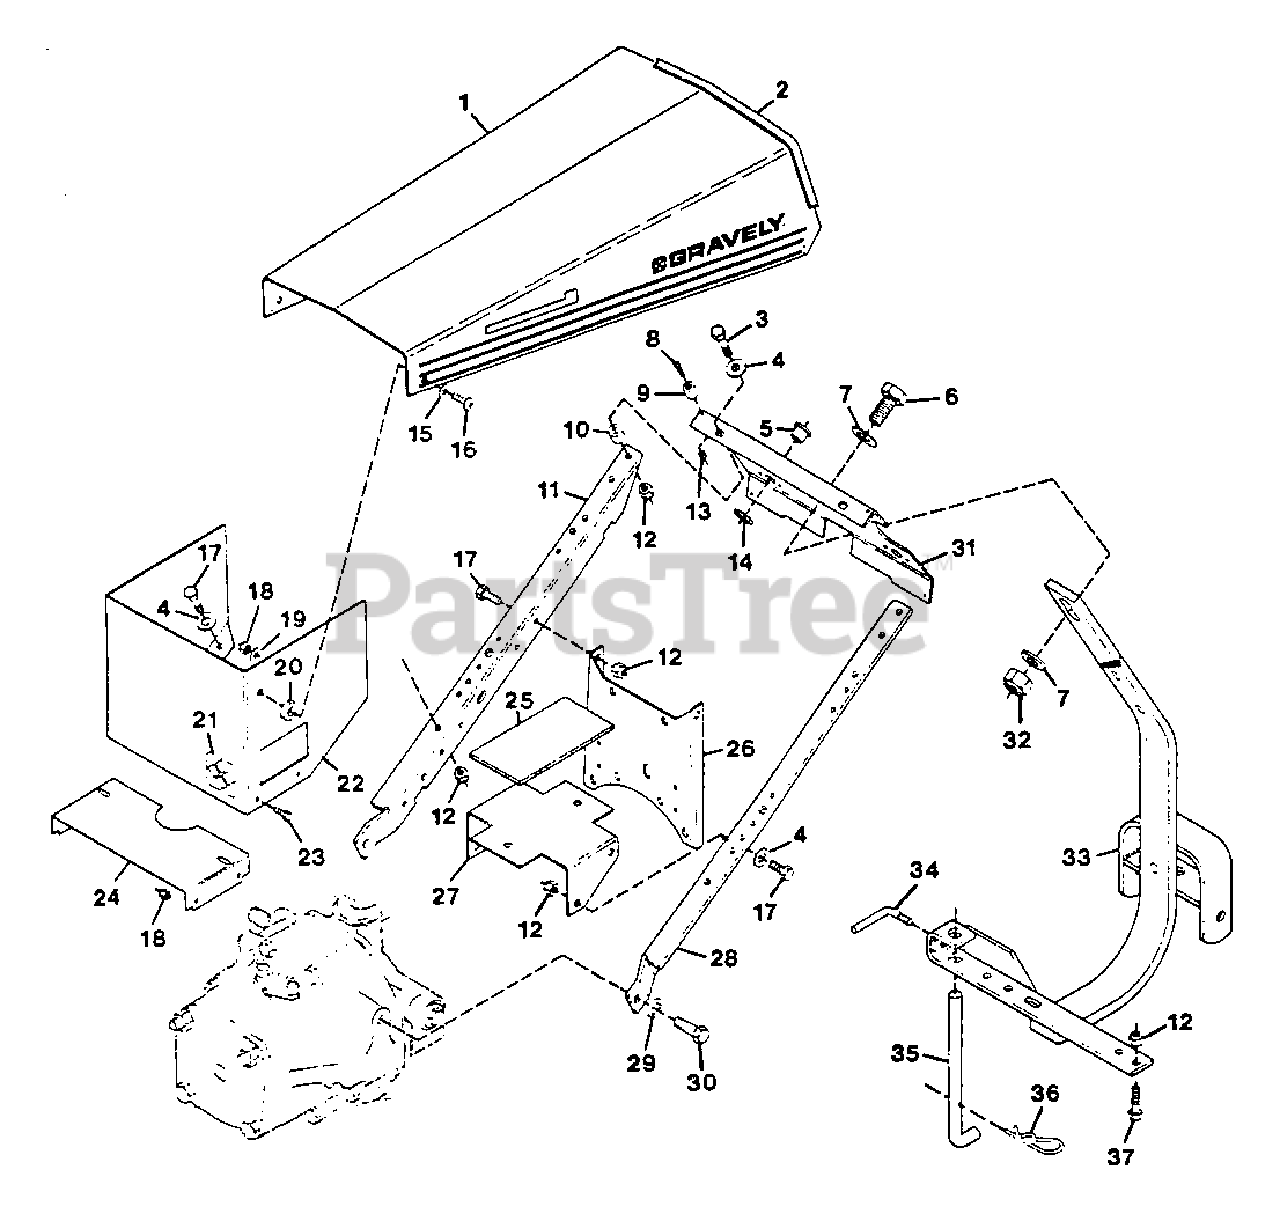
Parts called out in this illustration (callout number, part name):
1	Assembly, Hood
2	Ft. Strip, Cowl
3	Bolt, Hex 3/8-16x1.50
4	Washer, Flat .406x.812x.065
5	Bushing, .513x.750x.625
6	Bolt, Hex 5/8-11x2.00
7	Washer, Flat .656x1.250x.100
8	Screw, Mach. 6-32x.625 PHD
9	Bumper
10	Bushing, Reverse Idler
11	Support, Handlebar R.H.
12	Nut, Lock 3/8-16
13	Nut, Mach. Lock 6-32
14	Ring, Retaining
15	Washer, Flat .281x.625x.065
16	Screw, Mach. 1/4-20x1.00 PHD
17	Bolt, Hex 3/8-16x.875
18	Nut, Lock 1/4-20 (Manual)
18	Nut, Lock 1/4-20 (Electric)
19	Washer, Flat .313x.875x.065
20	Bushing, Hood
21	Decal
22	Support, Hood
23	Bolt, Hex 1/4-20x.625 (Electric)
24	Bracket (Electric)
25	Pad, Gas Tank
26	Bracket
27	Bracket, Tank Support
28	Support, Handlebar LH.
29	Washer, Lock 1/2 Reg.
30	Bolt, Hex 1/2-13x1.00
31	Plate, Silk Screen (Manual)
31	Plate, Silk Screen (Electric)
32	Nut, Lock 5/8-11
33	Weldment, Hitch
34	Handle, Adjusting
35	Stand, Kick
36	Pin, Hair
37	Bolt, Hex 3/8-16x2.00
NS	Decal, 7240 KDE (Electric)
NS	Decal, Side Stripe
NS	Decal, Gravely
NS	Decal, 8 Lead (4-Speeds)
NS	Decal, Professional
NS	Decal, 7240 KD (Manual)
NS	Decal, Differential Lock (2-Speeds)
